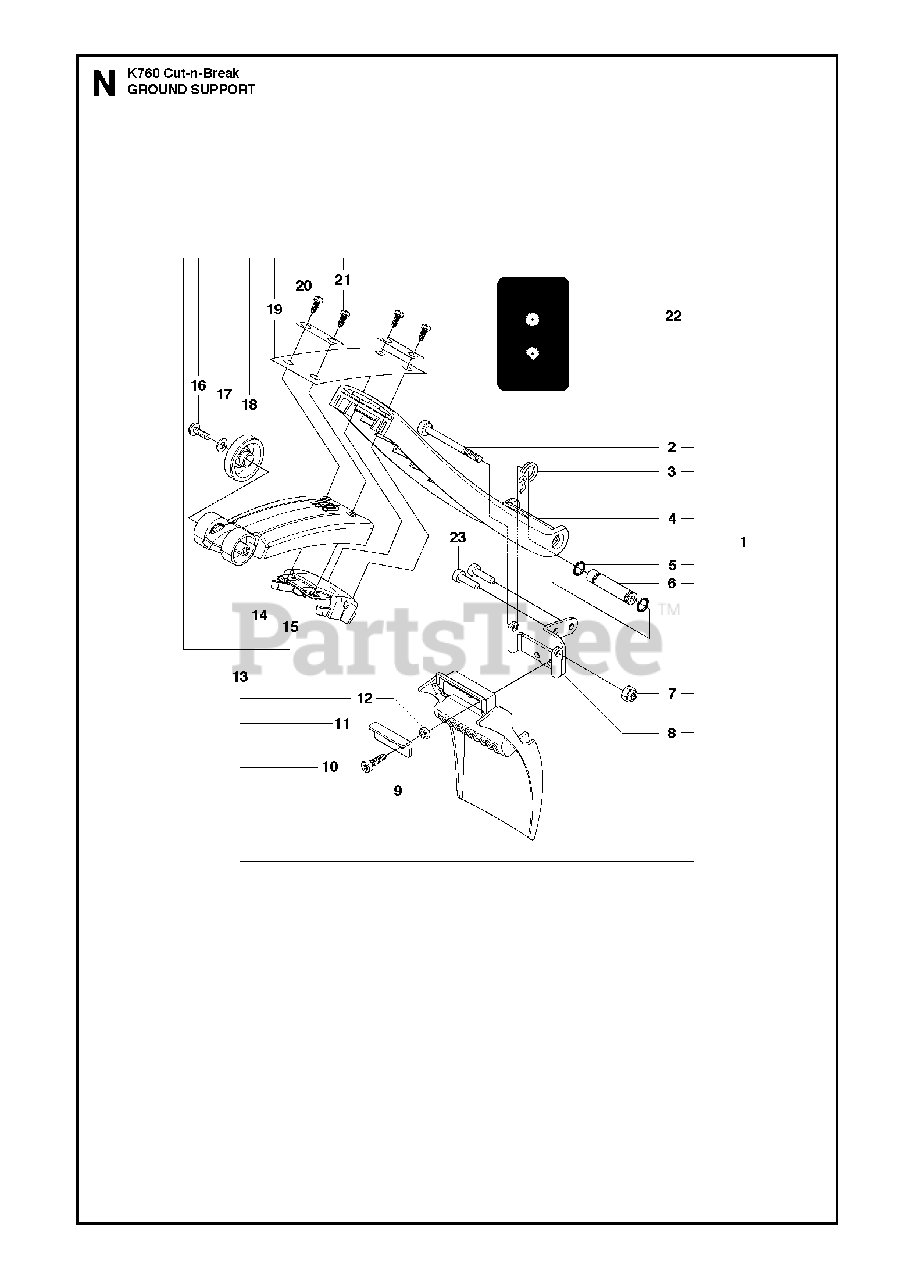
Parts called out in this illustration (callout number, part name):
1	SPRAY GUARDIncl. 2 - 13, 22
2	SCREW ITXSCM
10	SCREW ITXSCM
13	SPRAY GUARDIncl. 14 - 21
21	SCREW CRPANT
23	SCREW ITXSCM
